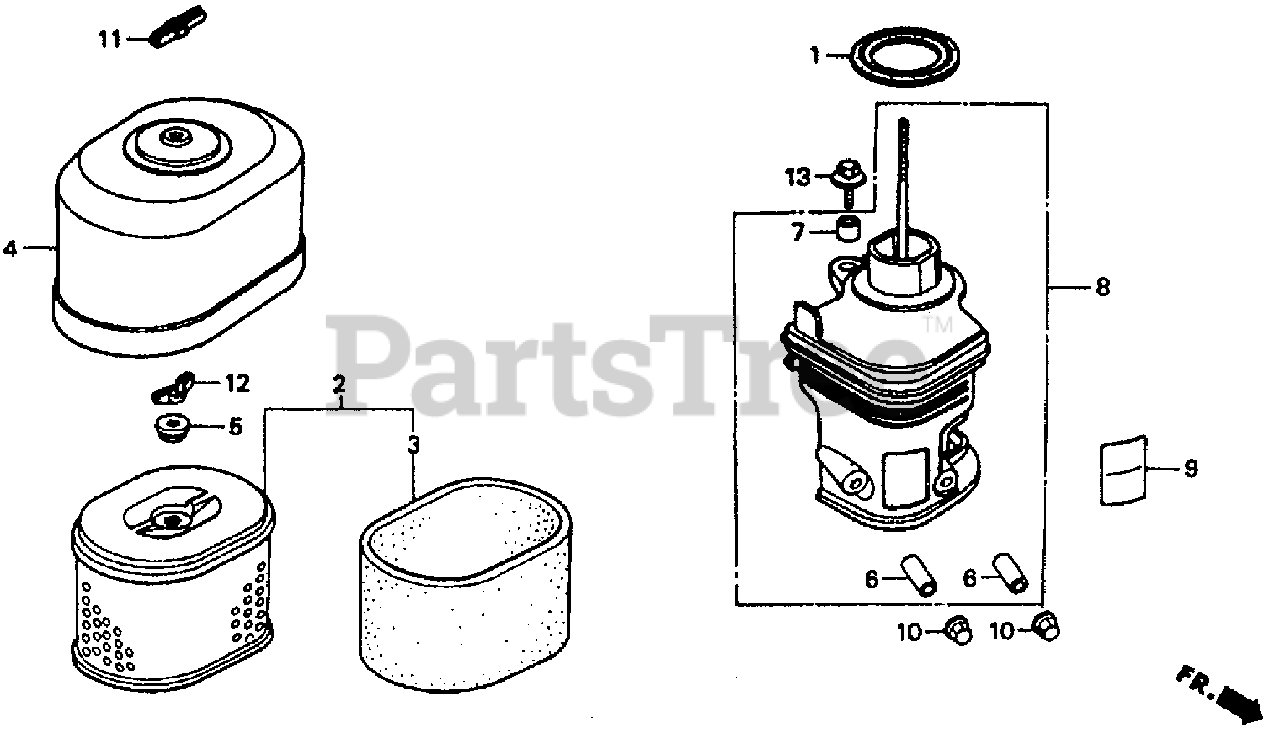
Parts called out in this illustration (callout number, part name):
1	GASKET, ELBOW
2	ELEMENT, AIR CLEANER (DUAL)
3	FILTER (OUTER)
4	COVER, AIR CLEANER (DUAL)
5	GROMMET, AIR CLEANER
6	COLLAR, AIR CLEANER
7	COLLAR B, AIR CLEANER
8	ELBOW, AIR CLEANER
9	MARK, CHOKE (EXTERNAL)
10	NUT, CAP (6MM)
11	WINGNUT, AIR CLEANER COVER
12	WINGNUT, TOOL BOX SETTING
13	BOLT-WASHER (6X20)
